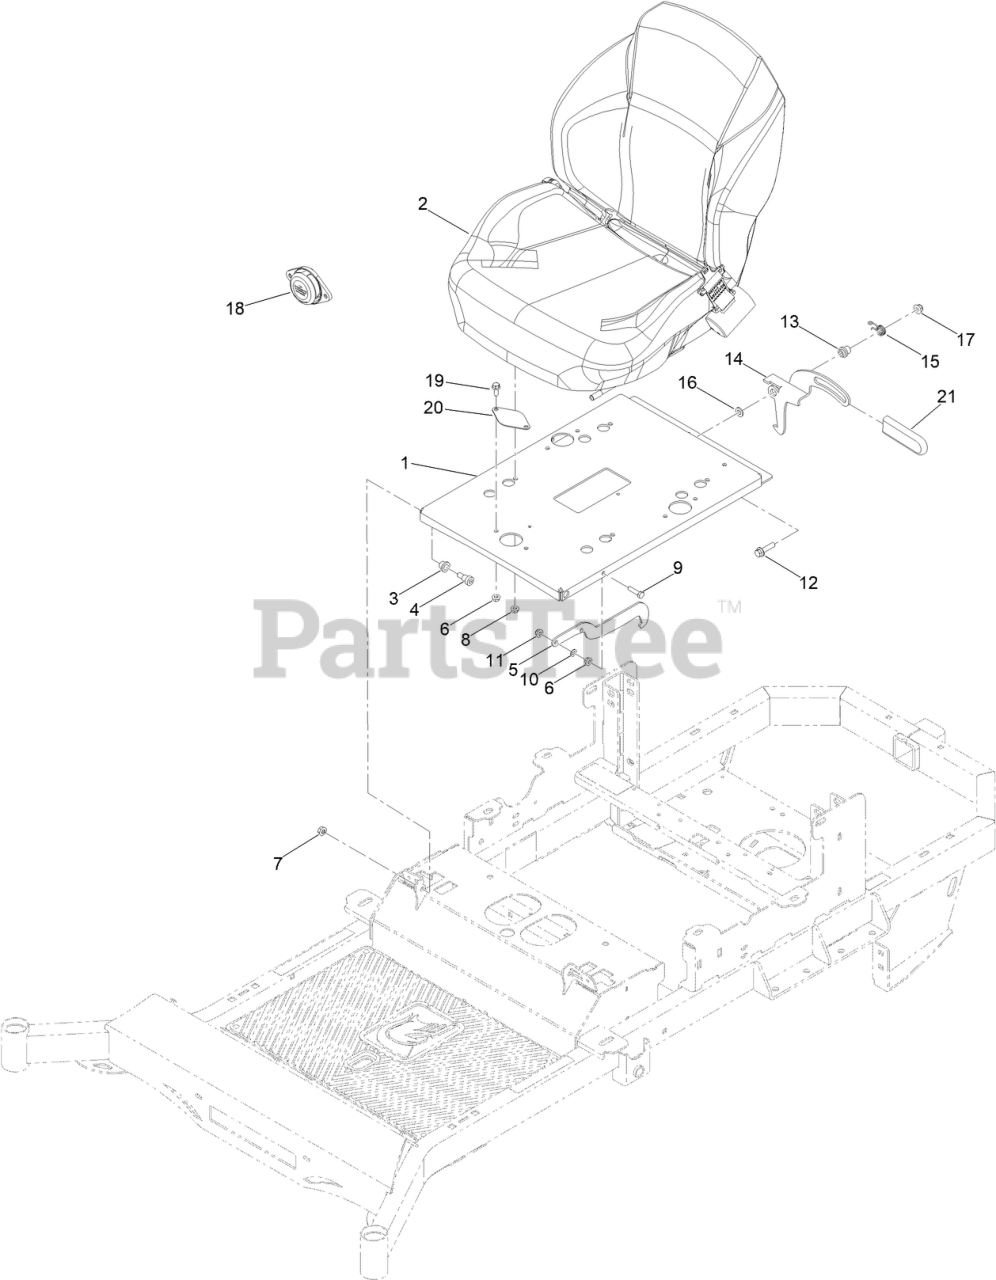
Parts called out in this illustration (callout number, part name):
1	NON 360 SEAT BASE PLATE SAFTY DECAL ASM-
2	RT PRO SEAT
3	1/2IN ID X 5/8IN OD X 1/2IN FLANGE BUSH
4	1/2 X 1/2 SOCKET SHOULDER BOLT ZC YELLOW
5	MWR SEAT LATCH HOOK PAINT
8	5/16-18 NYLON INSERT FLANGE L/NUT ZC
9	SCREW-HH
10	.312IDX.625ODX.062 THK THRUST BRG OI BRZ
11	NUT-HF, NI
12	SCREW-HHF
13	BUSHING-LATCH, SEAT
14	BRACKET-LATCH
15	SPRING-TORSION, LATCH
16	WASHER-FLAT
17	NUT-HF, NI
18	MWR SEAT SWITCH
19	SCREW-HHF
20	2020 RT/SRT UNIV FLOAT SEAT CVR PLT
21	STAND UP MWR BRAKE ARM GRIP
